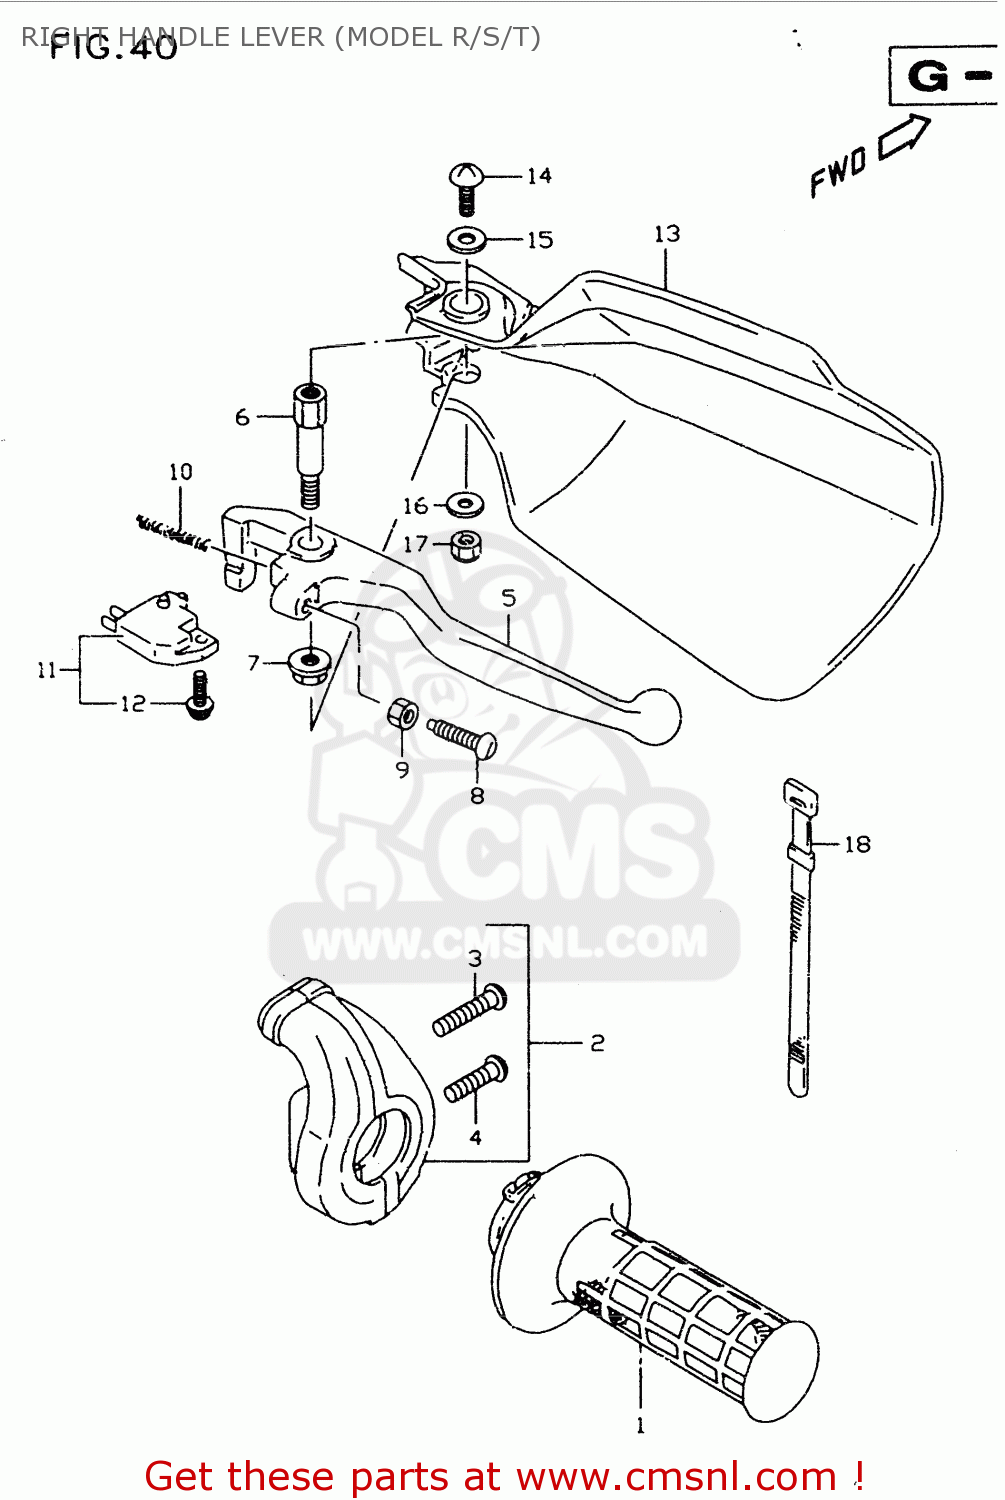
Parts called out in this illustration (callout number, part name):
1	GRIP,THROTTLE
2	CASE ASSY,THROTTLE
3	SCREW(5X25)
4	SCREW 5X20
5	LEVER,BRAKE
6	BOLT,BRAKE LEVER PIVOT
7	NUT 6MM
8	BOLT,ADJUST
9	NUT ,5MM
10	SPRING,RETURN
11	SWITCH ASSEMBLY,STOP
12	SCREW
13	COVER,KNUCKLE,R
14	SCREW
15	WASHER (5.5X16X1.2)
16	WASHER (6.5X17X1.6)
17	NUT 6MM
18	CLAMP(L:120)
